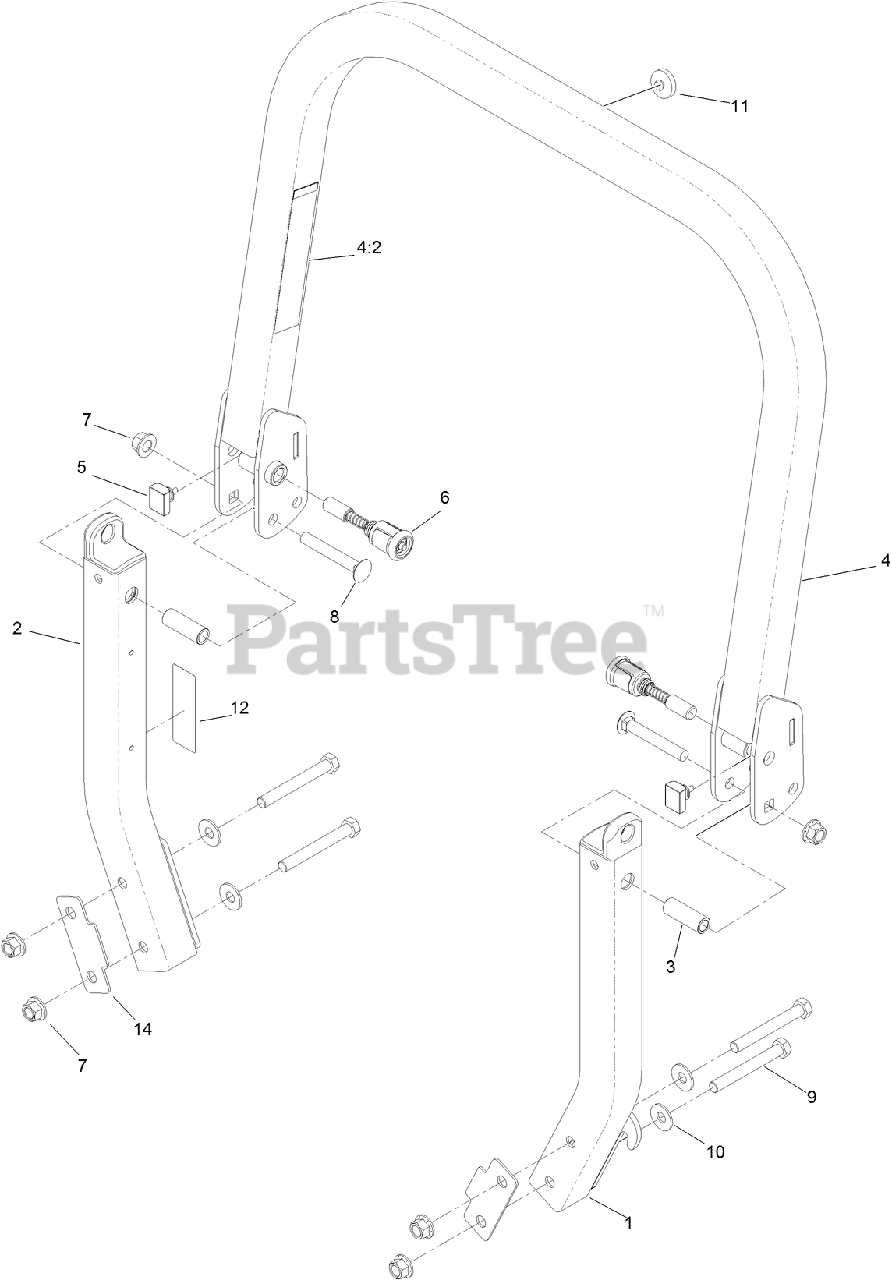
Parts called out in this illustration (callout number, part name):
1	LEG-ROPS, LH
2	LEG-ROPS, RH
3	SPACER
4	UPPER ROPS ASM
4:2	DECAL-WARNING
5	BUMPER-ROPS
6	PIN-SPRING
7	NUT-LOCK
8	SCREW-CARR
9	SCREW-HH
10	WASHER-SPRING
11	BUMPER-PUSH-IN, RUBBER
12	DECAL-CAUTION, FUEL VENT
14	SPACER
